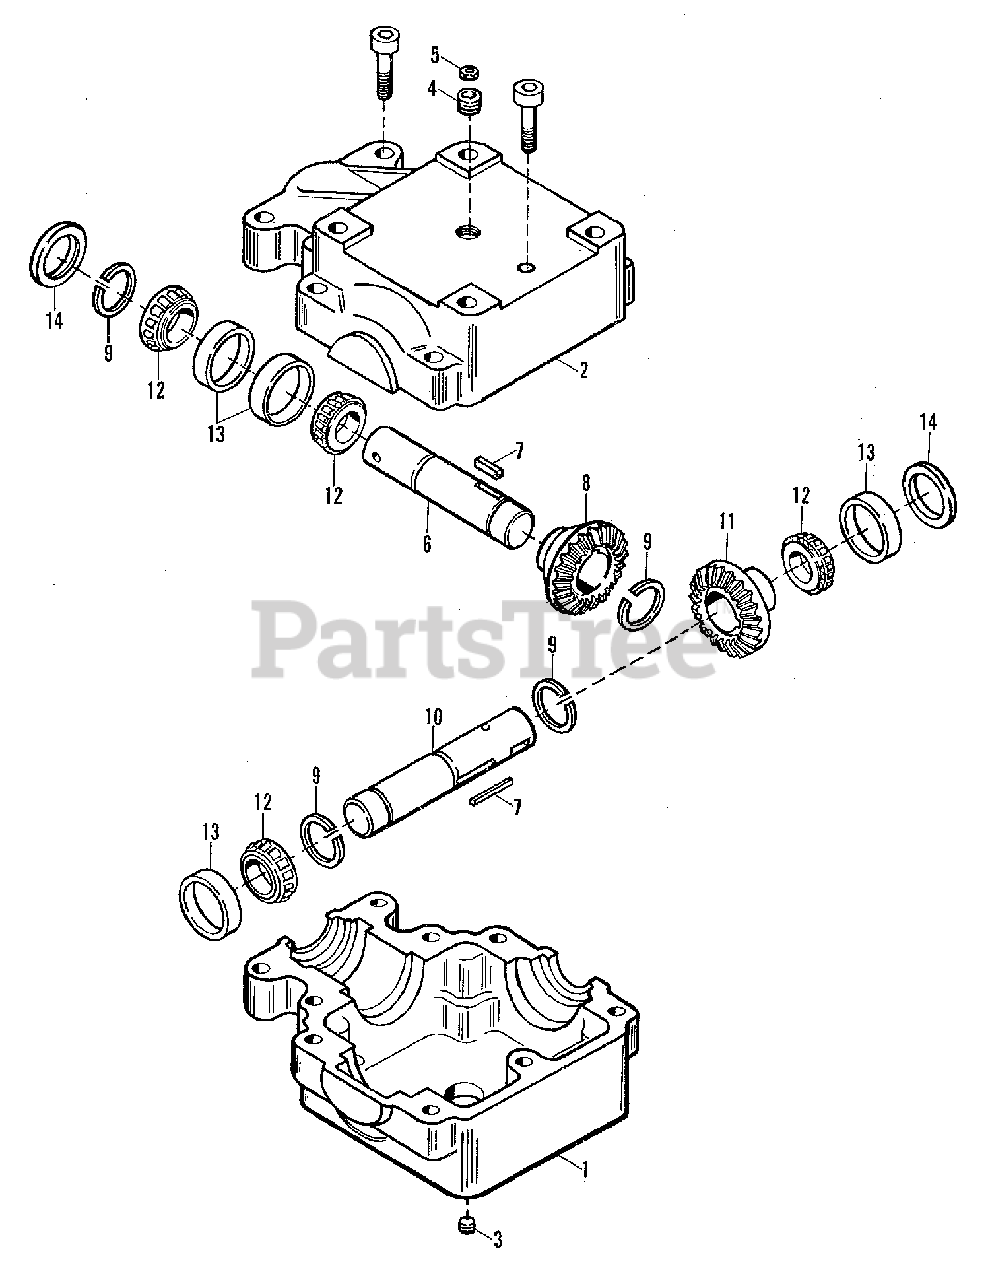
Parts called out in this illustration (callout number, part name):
1	HOUSING, Half (Treaded Holes)
2	HOUSING, Half (Thru Holes)
2	CAPSCREW, Socket Head, 3/8NC x 1-1/2
2	CAPSCREW, Socket Head, 3/8NC x 2-1/2
4	BUSHING, Pipe Adapter
5	PLUG, Pressure Relief (5 P.S.I.)
6	SHAFT, Pinion
7	KEY, Woodruff
8	GEAR, Pinion
9	RING, Retaining
10	SHAFT, Cross
12	CONE, Bearing
13	CUP, Bearing
